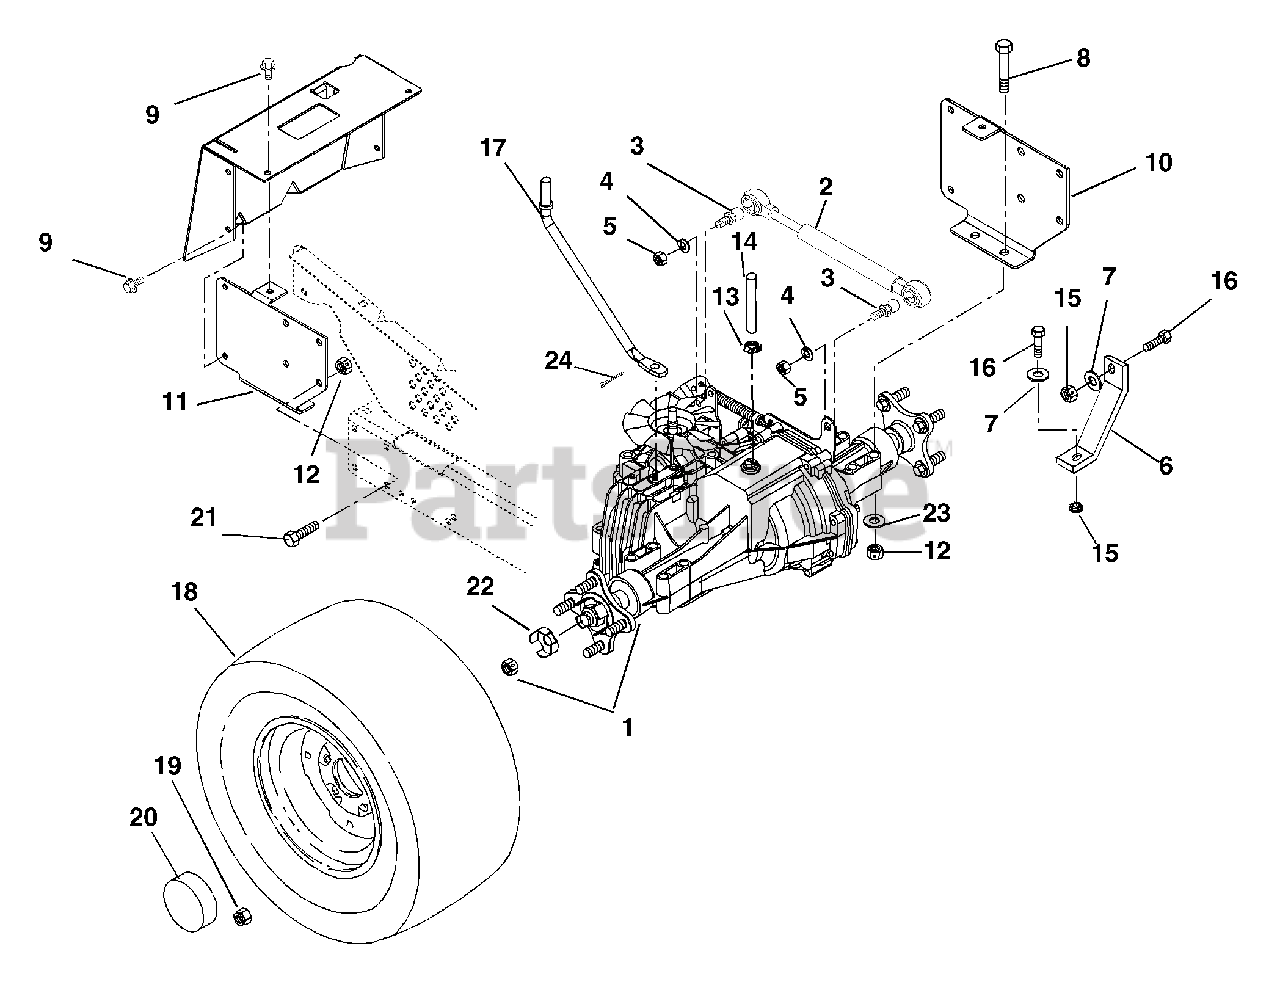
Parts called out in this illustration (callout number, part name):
1	TRANSAXLE-HYDR0-GEAR #319-3000
2	DAMPER - HYDRAULIC
3	STUD- BALL
4	WSHR-LK .312X.097 HVY YWZC
5	@NUT-HEX .31-18 YWZC
6	BRACE, LH TRANSAXLE
7	@WSHR-FL-STL.344X.688X.065YWZC
8	@BLT-HEX .38-16X3.00 GR5 YWZC
9	@SCR-TAP .38-16X.75 HWH TR YWZ
10	MOUNT, AXLE LH
11	MOUNT, AXLE RH
12	@NUT-LK-CTR .38-16 YWZC
13	CLAMP-HOSE WRM .38/.62X.50 #10
14	HOSE, VENT
15	@NUT-LK-CTR .31-18 YWZC
16	@BLT-HEX .31-18X.75 GR5 YWZC
17	ROD-DUMP VALVE
18	TIRE/WHEEL ASSEMBLY 10.50X23
19	NUT-LUG .437-20 YWZC
20	REAR HUB CAP
21	@BLT-HEX .38-16X.75 GR5 YWZC
22	SPINDLE CUP
23	@WSHR-FL-STL.406X.812X.065 YWZ
24	@PIN-CTR .09X.75 EXTPRSQCT YWZ
